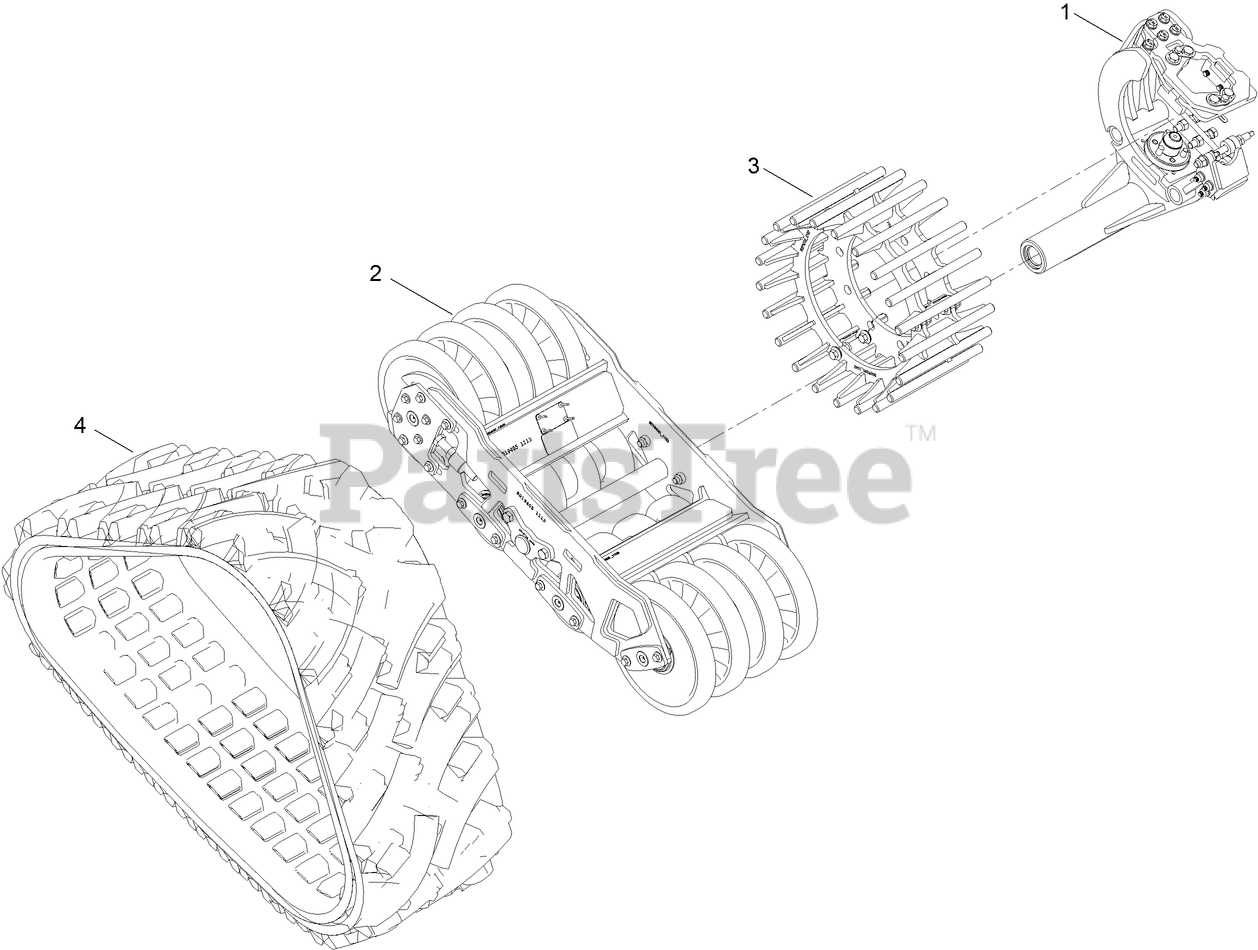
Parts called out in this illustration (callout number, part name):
1	FRONT LEFT AND REAR RIGHT ATTACH ASM
2	CHASSIS ASSEMBLY
3	SPROCKET ASM-21 TOOTH
4	TRACK-RUBBER, 511E, 19.5 IN
